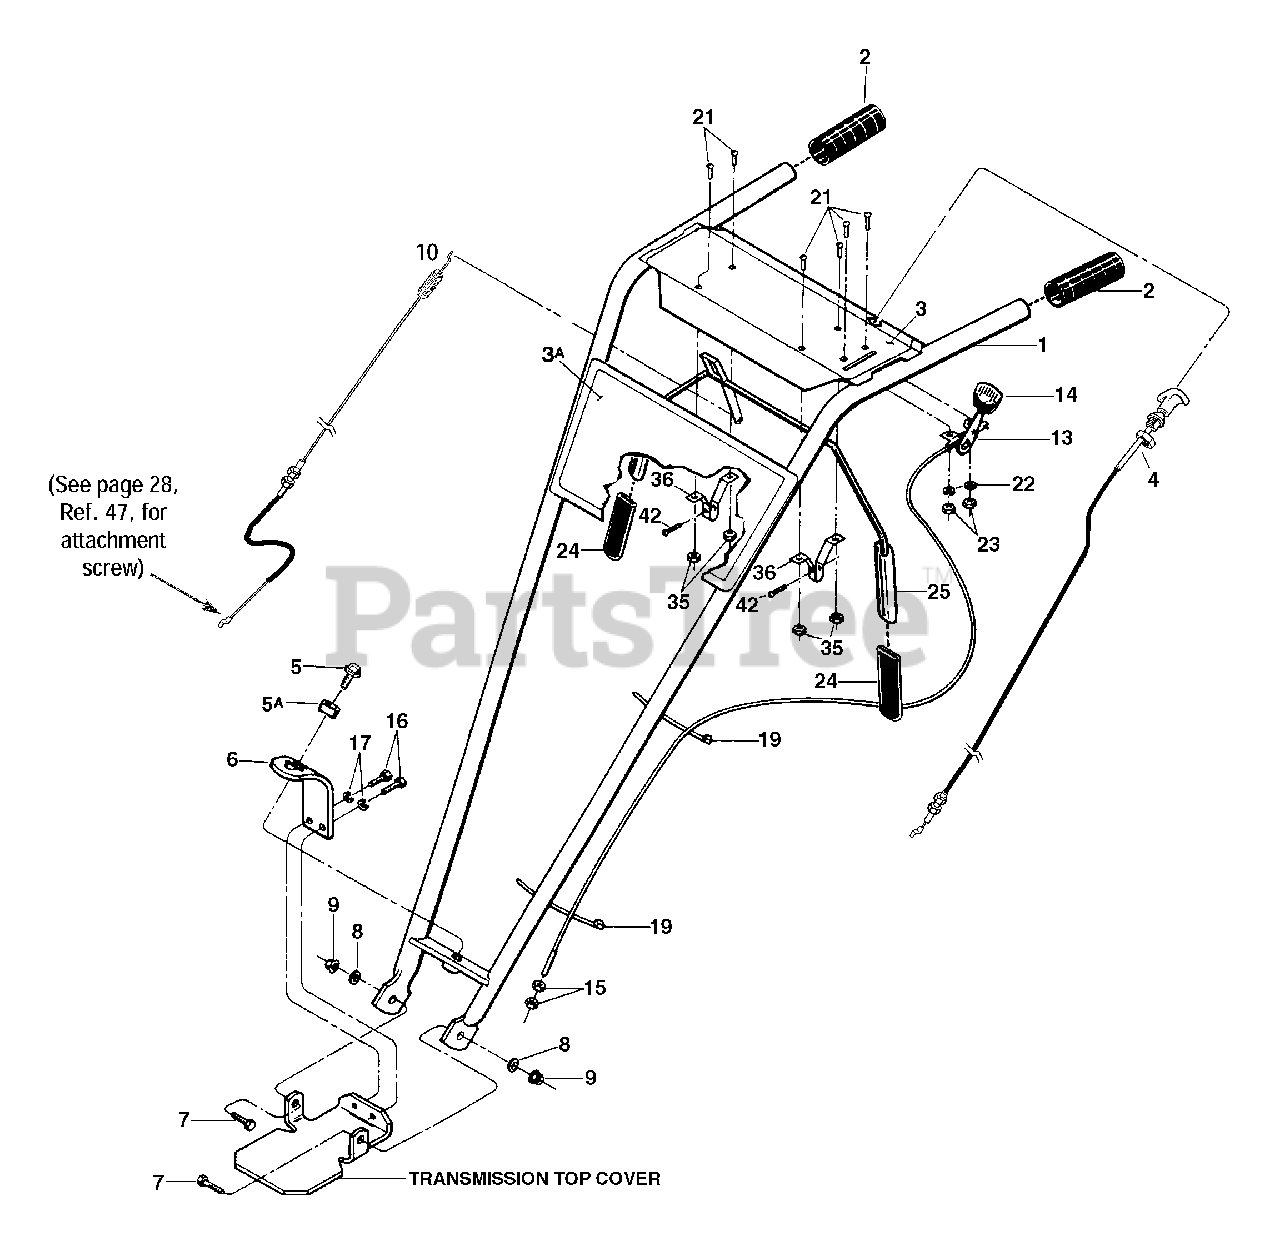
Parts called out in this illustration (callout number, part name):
1	Handlebars
2	Grip
3	Decal, Control Panel
3A	Decal, Model Name/Logo
4	Reverse Clutch Control Cable
5	Height Adjustment Screw
5A	Washer, Keyed
6	Bracket, Handlebar Height Adjustment
7	Hex Hd. Screw, 3/8-16 x 1
8	Washer, Plain (flat) 3/8, S.A.E.
9	Hex Locknut, 3/8-16
10	Cable, Forward Clutch Control
13	Wheel Gear Control and Cable Assy.
14	Knob, Wheel Gear Control Lever
15	Hex Nut, 5/16-24
16	Hex Hd. Screw, 3/8-16 x 3/4
17	Lockwasher, 3/8
19	Cable Ties, Plastic
21	Round Hd. Screw, #10-32 x 1/2
22	Lockwasher, #10
23	Hex Nut, #10-32
25	Bail, Forward Clutch Control
36	Bracket, Bail Support
42	Hex Flange Screw, self-tapping, 1/4-20 x 1/2
